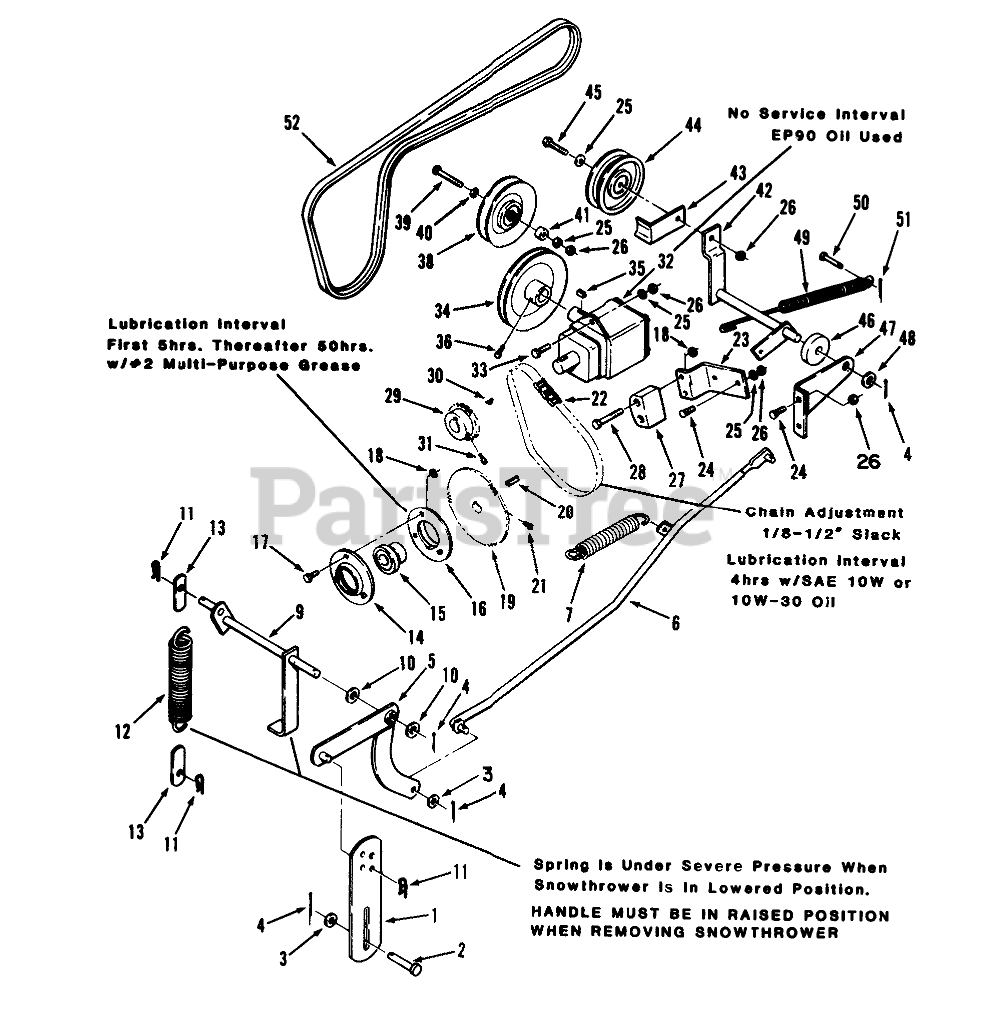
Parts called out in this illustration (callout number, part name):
1	LINK-LIFT R
2	CLEVIS PIN
3	Washer
5	WLDMT-SNOWTHWR LI R
6	WLDMT-LIFT ROD R
7	SPRING
9	WLDMT-SPRING SUPP R
10	Washer
11	Hairpin Cotter
12	SPRING
13	RETAINER-SPRING R
14	Flange
15	BEARING AND COLLAR
16	FLANGE-RELUBE
17	BOLT-CARR
18	NUT-LOCK, NI
19	SPROCKET-33T
20	KEY
21	Screw-Sq. Hd. Set
22	CHAIN
23	BRACKET-TIGHTENER R
24	BOLT-CARR
25	WASHER-FLAT
26	NUT-LOCK, NI
27	Chain Tightener
28	SCREW-HH
29	SPROCKET-15 T
30	KEY-HI PRO
31	SCREW-SET
32	GEAR-BOX L.H.
33	BOLT-CARR
34	Pulley-Gearbox
35	KEY-WOODRUFF
36	SCREW-SQH
38	"V" Pulley
39	SCREW-HH
40	WASHER
41	SPACER
42	WLDMT-IDLER ARM R
43	Spacer
44	PULLEY-FLAT IDLER
45	SCREW-HH
46	RUBBER WASHER
47	BRACKET-PIVOT R
48	WASHER
49	SPRING
50	Pin-Clevis
51	Pop Rivet
52	V-BELT 64 .5EL
